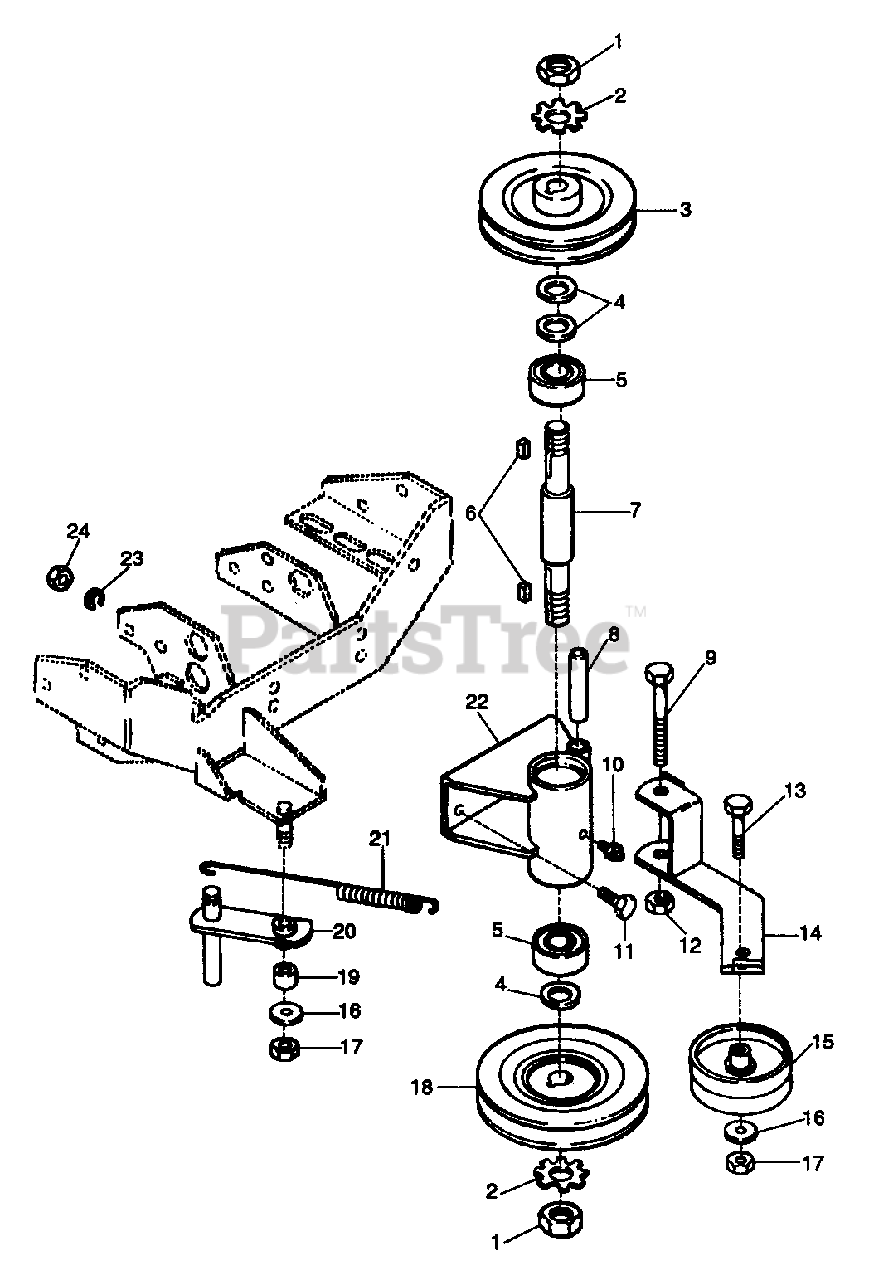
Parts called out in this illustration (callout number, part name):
1	NUT-JAM .75-10 PL
2	STAR WASHER
4	WSHR-FL-STL .755X1.250X.125
5	BRG-BALL .750X1.781X.61
6	KEY-SQ .188X.75X.188
7	JACKSHAFT
8	TUBE .392 X .50 X 2.20
9	BLT-HEX .38-16X2.75 PL GR5
10	SPIN DRIVE ZERK FITTING
11	BLT-HEX .31-18X1.00 PL GR5
12	NUT-LK-JAM-CTR .375-16 PL
13	BLT-HEX .38-16X1.75 PL GR5
14	IDLER ARM
15	IDLER-FLAT 3.25 X .38 NWHAMSHR
16	WSHR-FL-STL .390X.750X.125 PL
17	NUT-LK-CTR .375-16 GR A PL
19	.392 X .50 X .56
20	SPRING ARM
21	SG-TENS .095X.62X9.25 WLD ??
22	SPINDLE HOUSING
23	WSHR-LK .312X.097 PL HVY
24	NUT-HEX .312-18
